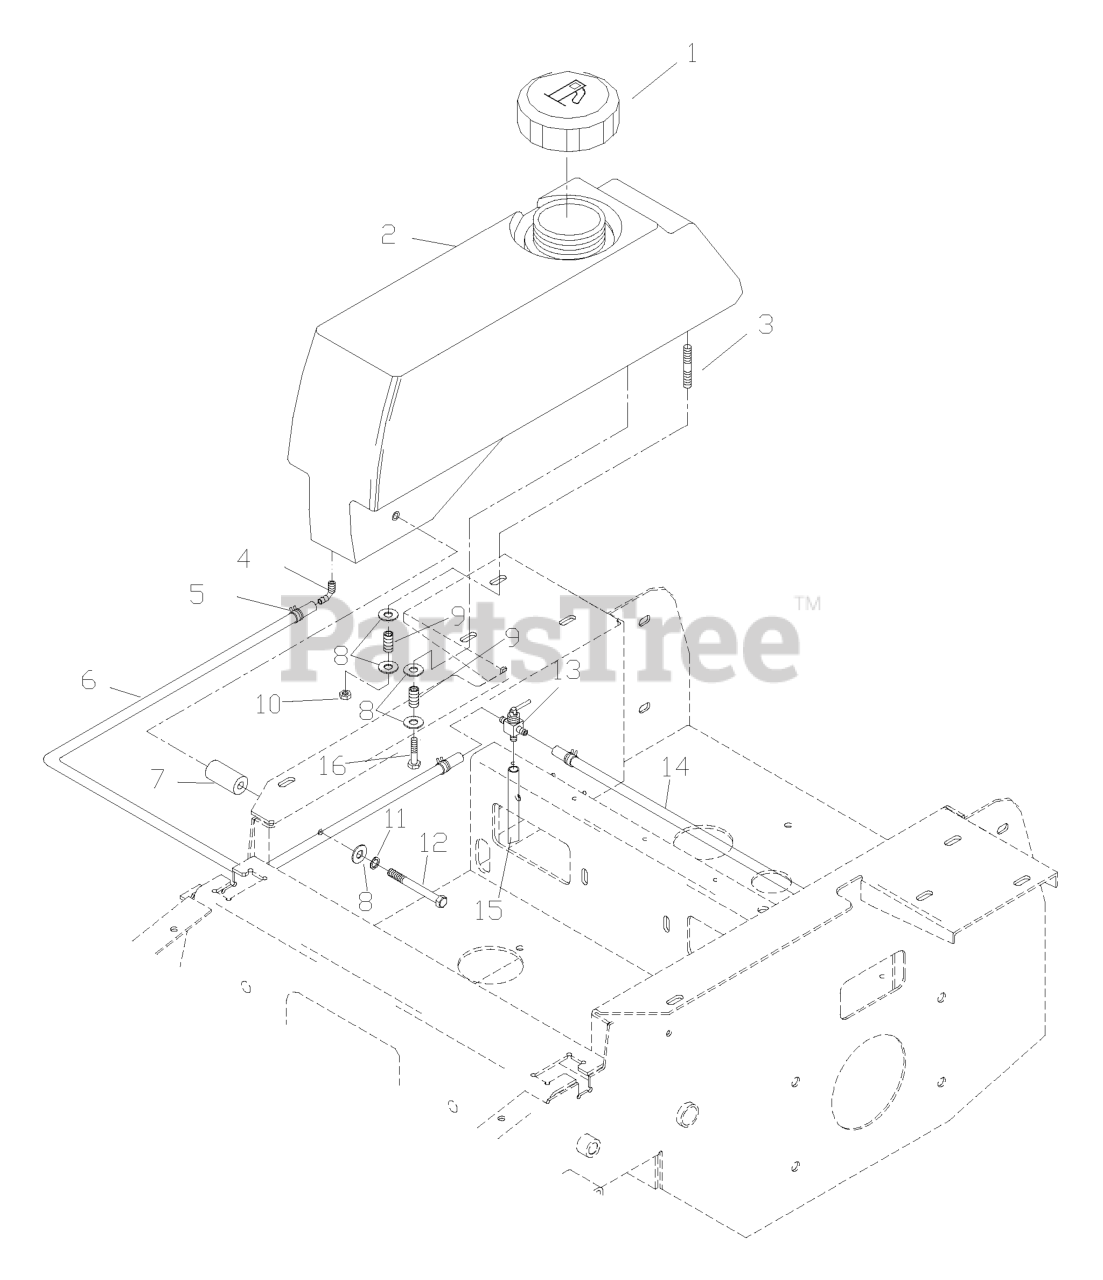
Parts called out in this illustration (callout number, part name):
1	FUEL CAP
2	FUEL TANK RT
2	LEFT TANK W/CUP HOLDER
3	STUD, 5/16C
4	HOSE BARB 90 DEGREE
5	HOSE CLAMP
6	FUEL LINE 29.5"
7	TANK SPACER
8	WASHER 5/16 FLAT
10	NUT 5/16C CENTERLOCK
11	WASHER.LOCK.HVY.HLCL.SPR.5/16
12	HCS 5/16C X 4
13	FUEL VALVE
15	FUEL LINE 16"
16	HCS 5/16C X 1
